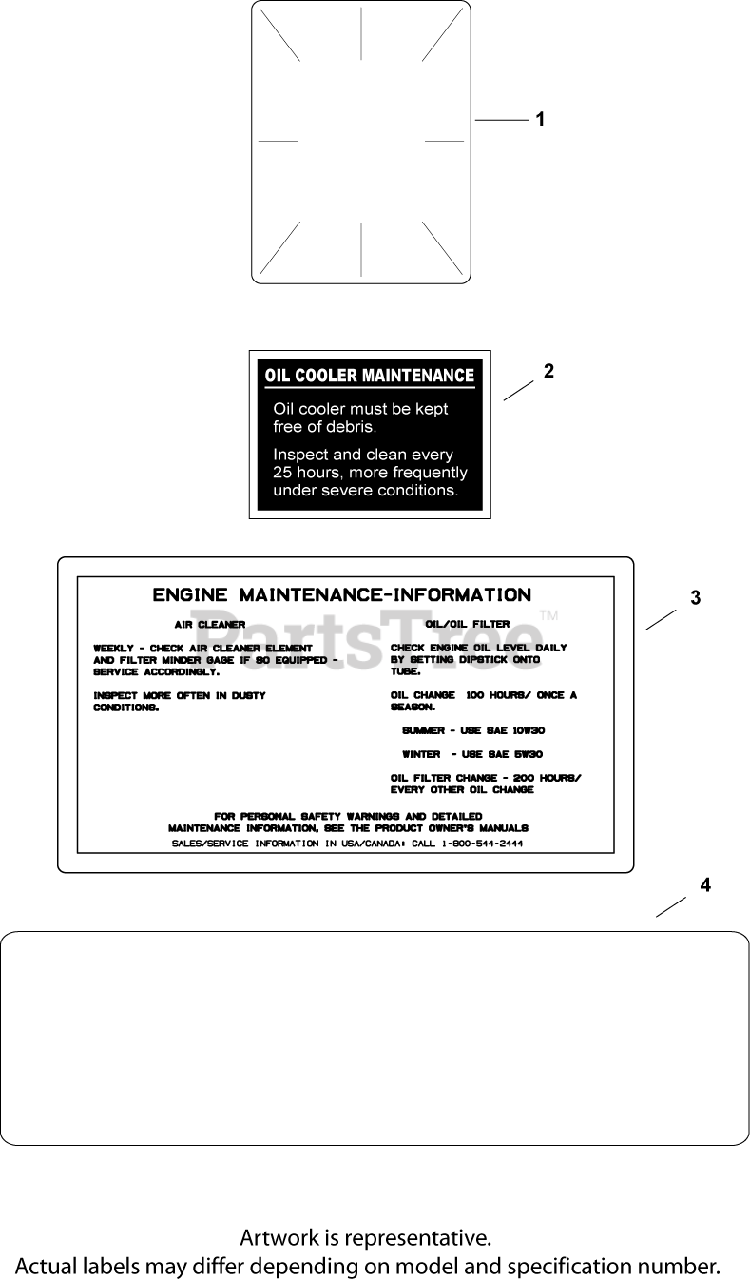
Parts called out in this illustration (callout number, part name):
1	DECAL, CLEAR LAMINATE USE 25 113 70-S
2	DECAL, OIL COOLER - (#DSC)
3	DECAL, AIR CLEANER - (#DSC)
4	DECAL, 28 HP - DISCONTINUED
